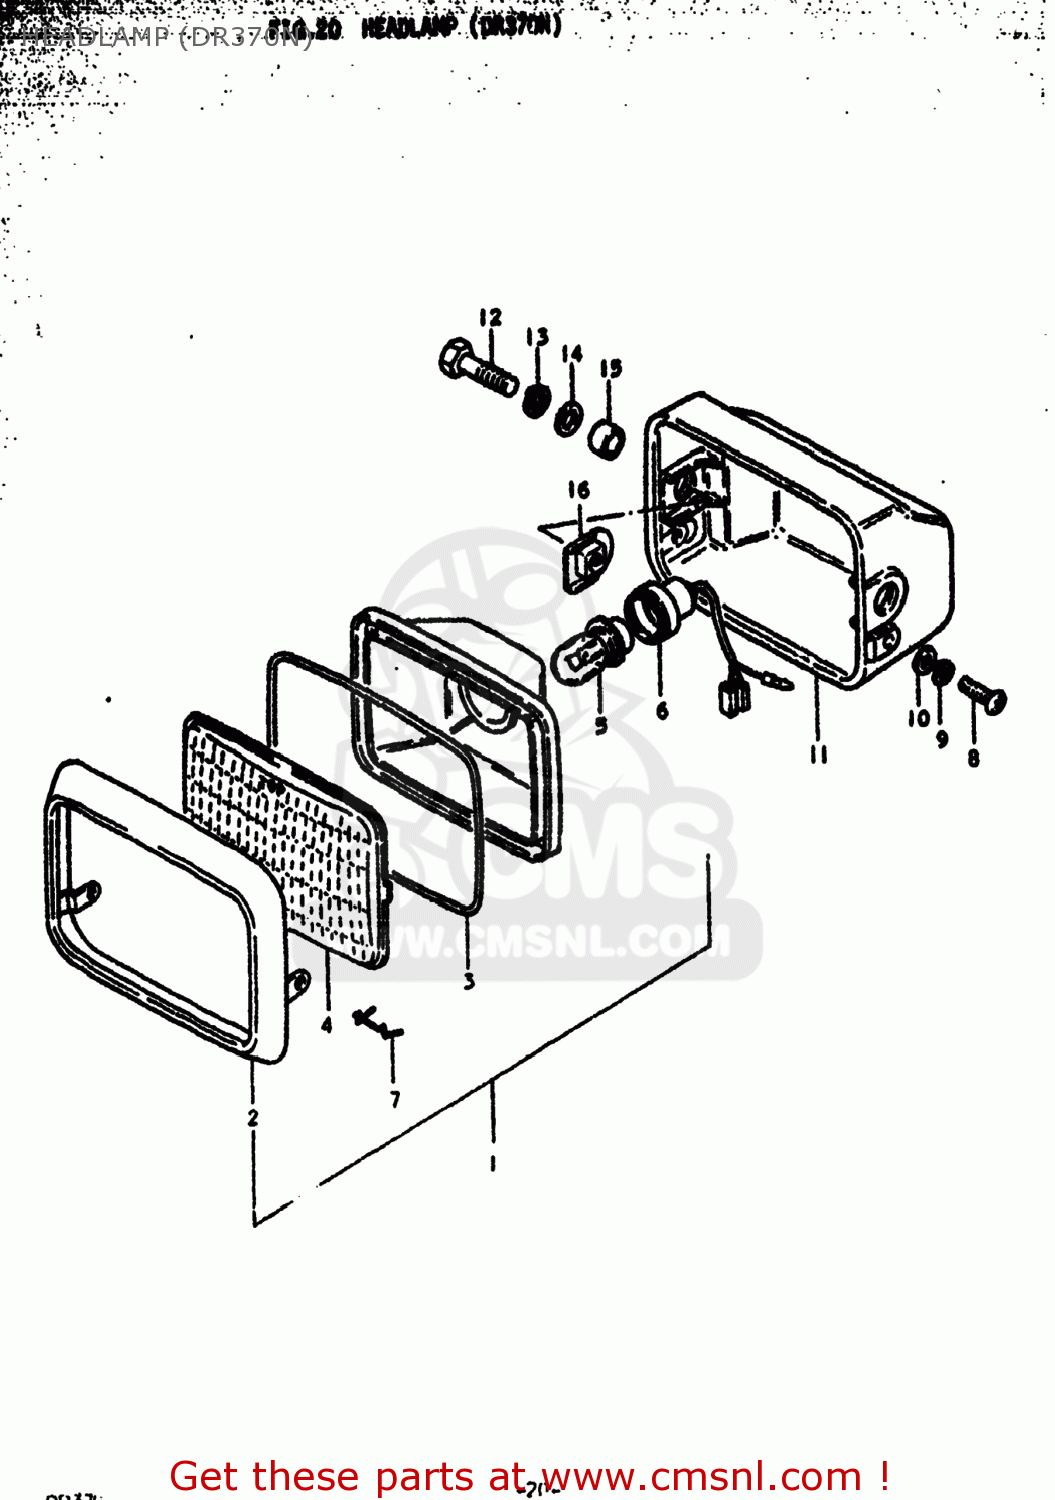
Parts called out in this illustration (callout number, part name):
1	LAMP ASSEMBLY,HEAD
2	RIM,HEADLAMP
3	GASKET,HEADLAMP LENS (NAS)
4	LENS,HEADLAMP (PLASTIC)
5	BULB(6V15/15W/STANLEY,A3598HA)
6	SOCKET,BULB
7	SPRING,HEADLAMP UNIT
8	SCREW
9	LOCK WASHER
10	WASHER
11	HOUSING,HEADLAMP
12	BOLT
13	LOCK WASHER
14	WASHER
15	SPACER (8.8X12X7)
16	PLATE,HEADLAMP HOUSING
